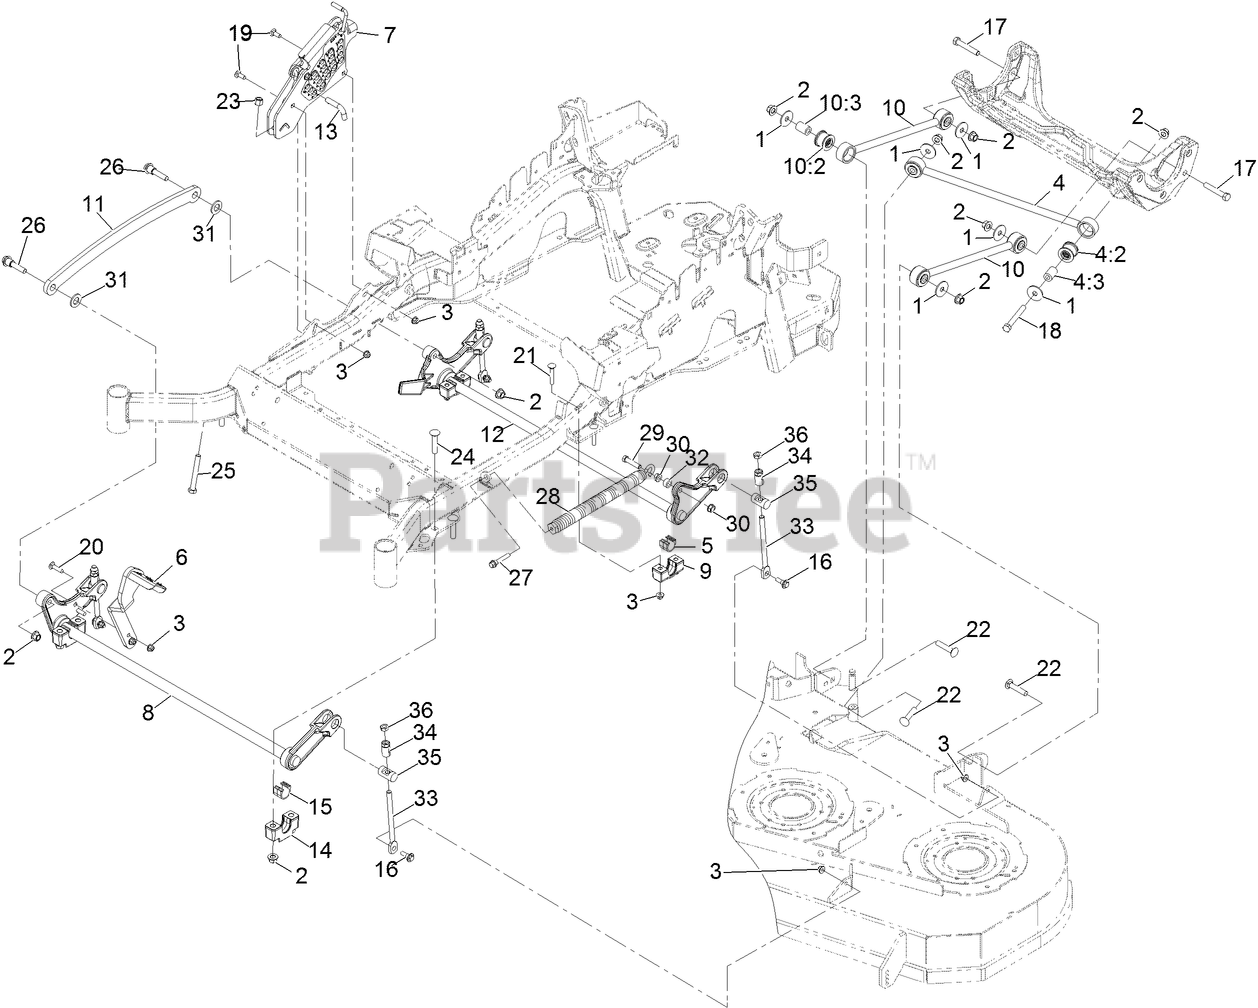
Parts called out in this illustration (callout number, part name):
1	WASHER-THRUST
2	Nut-Lock 1/2-13
3	NUT-HF, NI
4	PANHARD ROD ASM
4:2	BUSHING-SUSPENSION, RUBBER
5	BEARING-CROSS SHAFT, REAR
6	LEVER-FOOT
7	HOC ASM
8	DECKLIFT-FRONT
9	SUPPORT-CROSS SHAFT, BEARING REAR
10	DECK STRUT ASM
10:2	BUSHING-SUSPENSION, RUBBER
11	LINK-LIFT, DECK
12	LIFT-DECK, REAR
13	PIN-HOC
14	SUPPORT-CROSS SHAFT, BEARING
15	BEARING-CROSS SHAFT, FRON
16	SCREW-SHOULDER, HHF
17	SCREW-HH
18	SCREW-HH
19	BOLT-CARR
20	SCREW-CARR
21	Bolt-Carriage 3/8-16 X 2 1/4
22	SCREW-CARR
23	NUT-LOCK, NI
24	Bolt-Carriage 1/2-13 X 2 1/2 Spl Neck
25	BOLT-TAP
26	SCREW-HHF, SHOULDER
27	BOLT-SHOULDER
28	SPRING-EXTENSION
29	SCREW-HH
31	WASHER-FLAT
33	LINK-ADJUSTER, DECK LIFT
34	ADJUSTER-LIFT, DECK
35	TRUNNION
36	NUT-JAM
